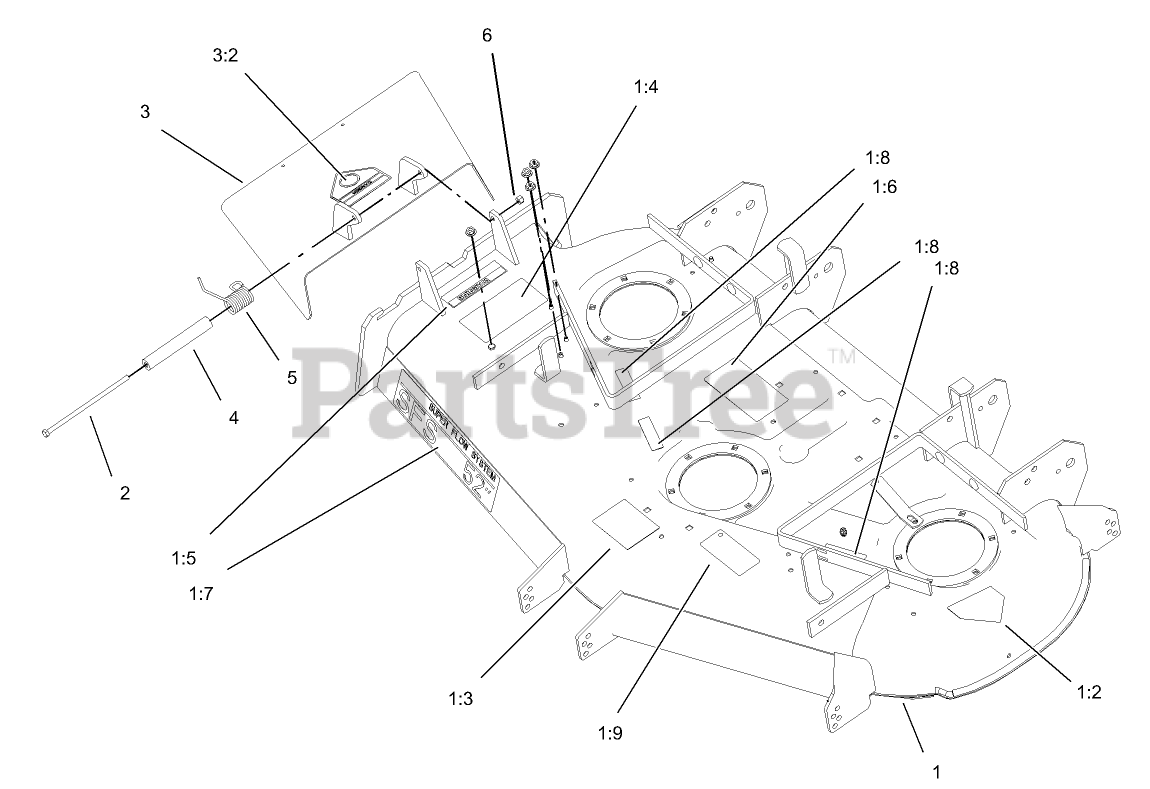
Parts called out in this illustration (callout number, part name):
1	Deck ASM
1:2	DECAL-DANGER
1:3	DECAL-WHEEL, GAGE
1:4	DECAL-DANGER, THROWN OBJECT
1:5	DECAL-WARNING
1:6	DECAL-BELT ROUTING
1:7	DECAL
1:8	DECAL-COVER, MISSING
1:9	DECAL-TORQUE, BLADE BOLT
2	SCREW-HH
3	Deflector ASM
3:2	DECAL-DANGER
4	SPACER
5	SPRING-TORSION
6	NUT-LOCK, NI
